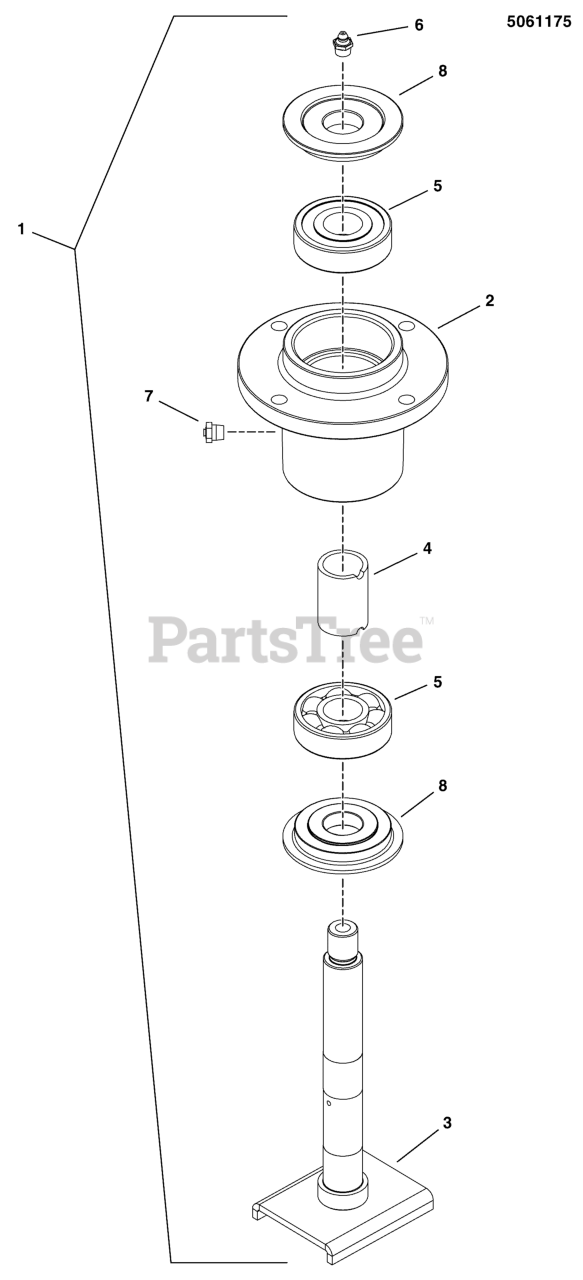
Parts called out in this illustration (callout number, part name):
1	ASSM, SPINDLE, BLADE SADDLE
2	HOUSING, SPINDLE
3	WELD, SHAFT, BLADE SADDLE
4	SPACER, 1.00 X 1.25 X 1.75
5	BEARING, .98 X 2.44 X .67
6	FITTING
7	FITTING, RELIEF, 1-5 PSI
8	TRASH SHIELD
